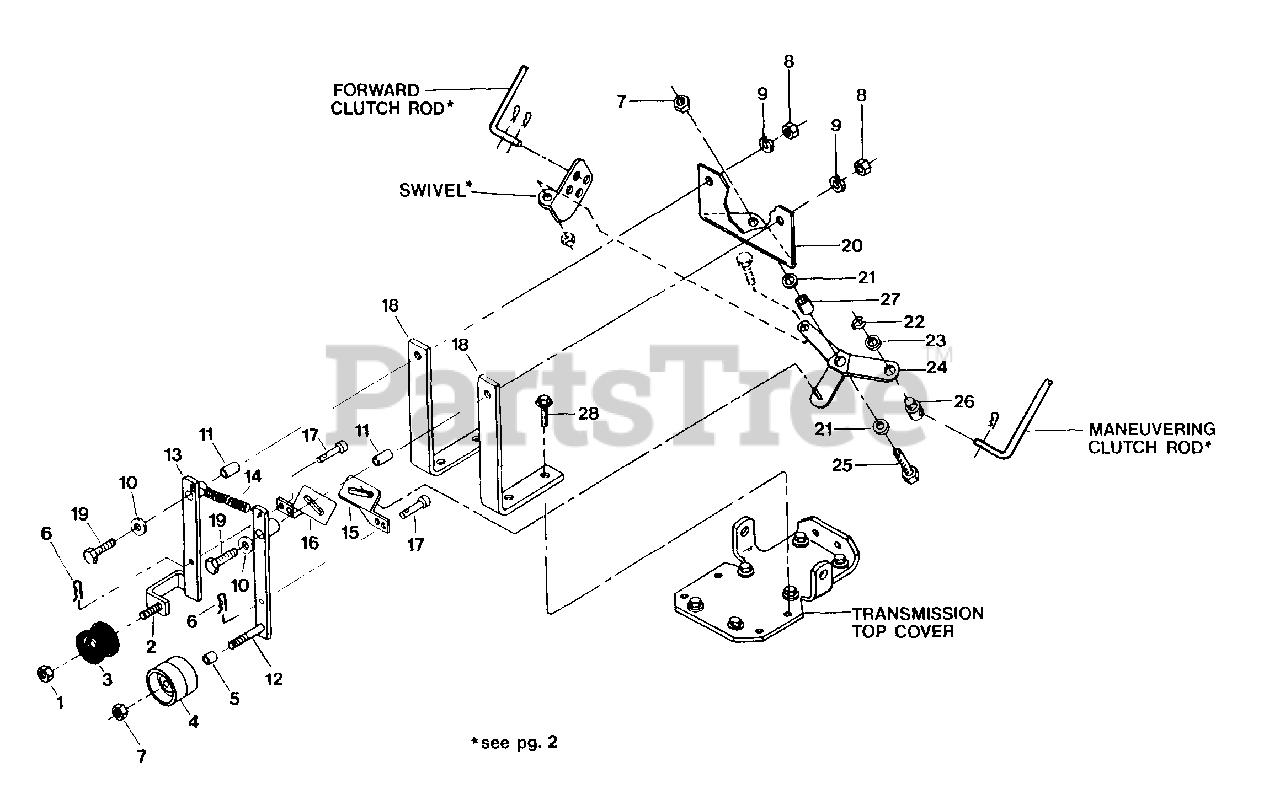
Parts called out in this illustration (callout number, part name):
1	Locknut-hex, 3/8-16
2	Screw-hex hd, 3/8-16 x 1-1/4
3	Pulley-idler, reverse tiller direction
4	Pulley-idler, forward tiller direction
5	Spacer
6	Hairpin Cotter
7	Locknut-hex, 3/8-16
8	Nut-hex, 5/16-18
9	Lockwasher-5/16
10	Washer-plain, 5/16
11	Pivot Busing
12	Idler Arm-left, forward tiller direction
13	Idler Arm-right, reverse tiller direction
14	Spring
15	Forward Link
16	Reverse Link
17	Pin
18	Mounting Bar
19	Screw-hex hd, 5/16-18 x 2-1/4
20	Shifting Base
21	Spacer-Bushing
22	Klip Ring
23	Washer-pivot
24	Bellcrank
25	Screw-hex hd, 3/8-16 x 1-1/4
26	Pivot-for Maneuvering Clutch lever
27	Bushing-bellcrank
28	Screw-flanged hex hd, 5/16-18 x 1
